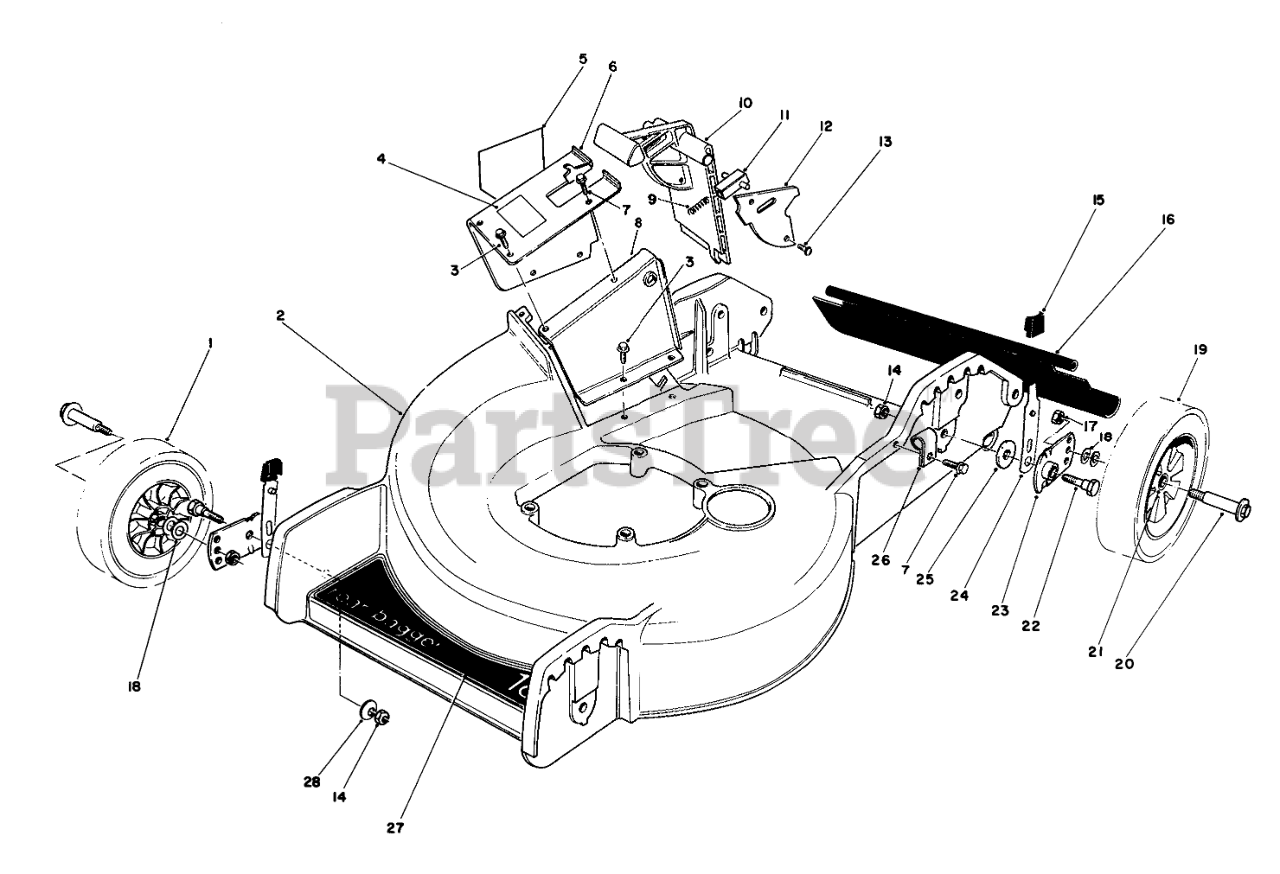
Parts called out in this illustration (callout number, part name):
1	Wheel & Tire Assembly (Incl. Ref. #21)
2	Housing
3	SCREW
4	Decal-Door
5	DECAL-DANGER
6	Tunne-Outer (Incl. Ref. #4 & 5)
7	SCREW
8	Tunnel-Inner
9	SPRING-COMPRESSION, LATCH
10	Door Mulching
11	Door Latch
12	Cover Door
14	NUT-LOCK, NI
15	KNOB-ARM
16	SHIELD - TRAILING
17	Nut
18	WASHER
19	Wheel & Tire Assembly (Incl. Ref. #21)
20	BOLT-WHEEL
21	BUSHING
22	5/16-18 PIVOT SCREW
23	PIVOT ARM ASSY
24	SPRING ARM ASM
25	PIVOT WASHER
26	CLAMP-NYLON
27	DECAL-DECK
28	WASHER-BELLEVILLE
